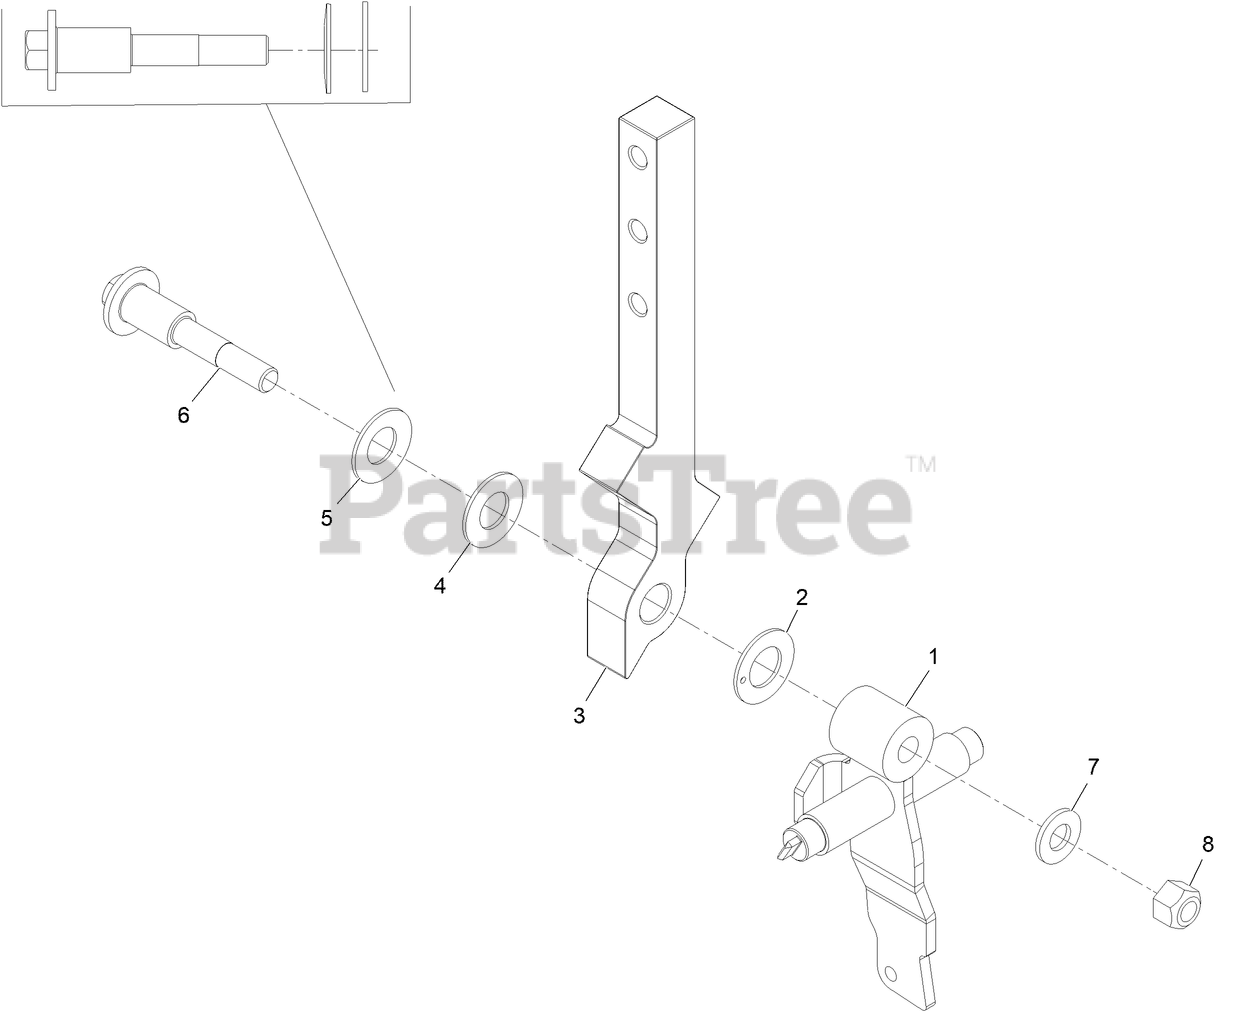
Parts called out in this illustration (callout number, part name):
1	Weld-Ctrl Arm LH
2	WASHER-FRICTION
3	ARM-CONTROL
5	WASHER-BELLEVILLE
6	BOLT-PIVOT
7	WASHER-FLAT
8	NUT-LOCK, CONE
